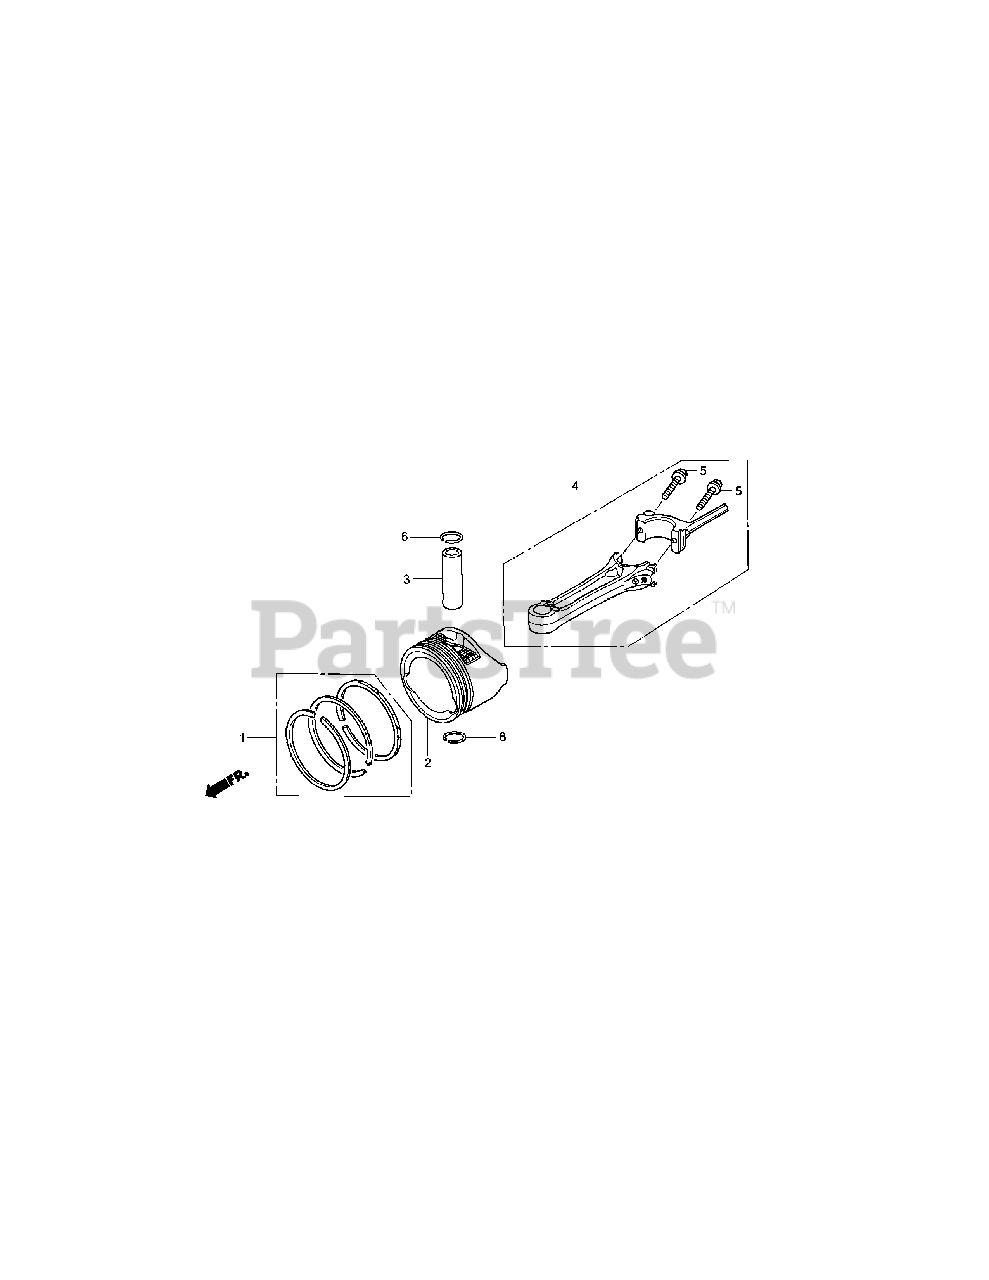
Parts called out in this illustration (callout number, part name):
1	Piston Ring Set
2	Piston
3	Piston Pin
4	Connecting Rod Assembly
5	Connecting Rod Bolt
6	Piston PinClip,13mm
